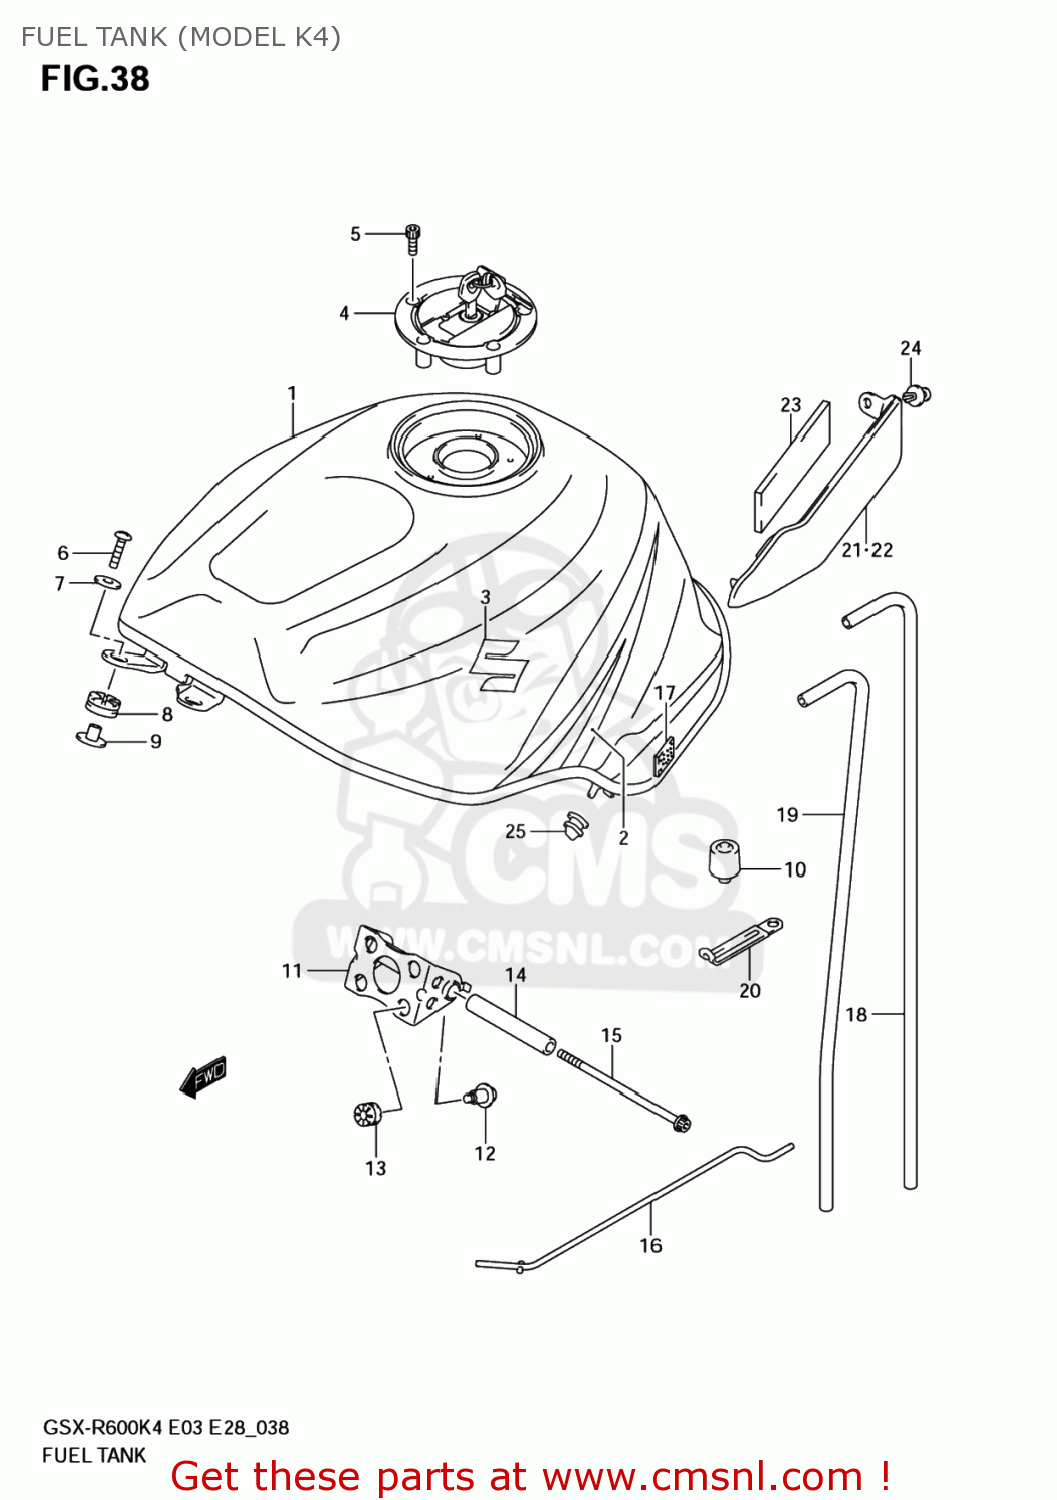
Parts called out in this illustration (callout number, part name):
1	TANK ASSY,FUEL(BLUE)
2	TAPE SET,FUEL TANK
3	EMBLEM,FUEL TA
4	CAP SET,FUEL TANK
5	BOLT(5X20)
6	SCREW(6X25)
7	WASHER(6.5X22X1.6)
8	CUSHION,FUEL TANK FR
9	SPACER,FUEL TANK FR
10	CUSHION,FUEL TANK RR
11	BRACKET,FUEL TANK NO.1
12	SCREW,FUEL TAN
13	CUSHION
14	SPACER,FUEL TANK RR
15	BOLT(6X110)
16	STAY,FUEL TANK
17	FASTENER
18	HOSE,WATER DRAIN
19	HOSE,FUEL TANK BREATHER
20	CLAMP(L:65)
21	COVER,FUEL TANK,R
22	COVER,FUEL TANK,L
23	CUSHION,FUEL TANK SIDE
24	CLIP(GRAY)
25	CUSHION,FUEL TANK COVER
